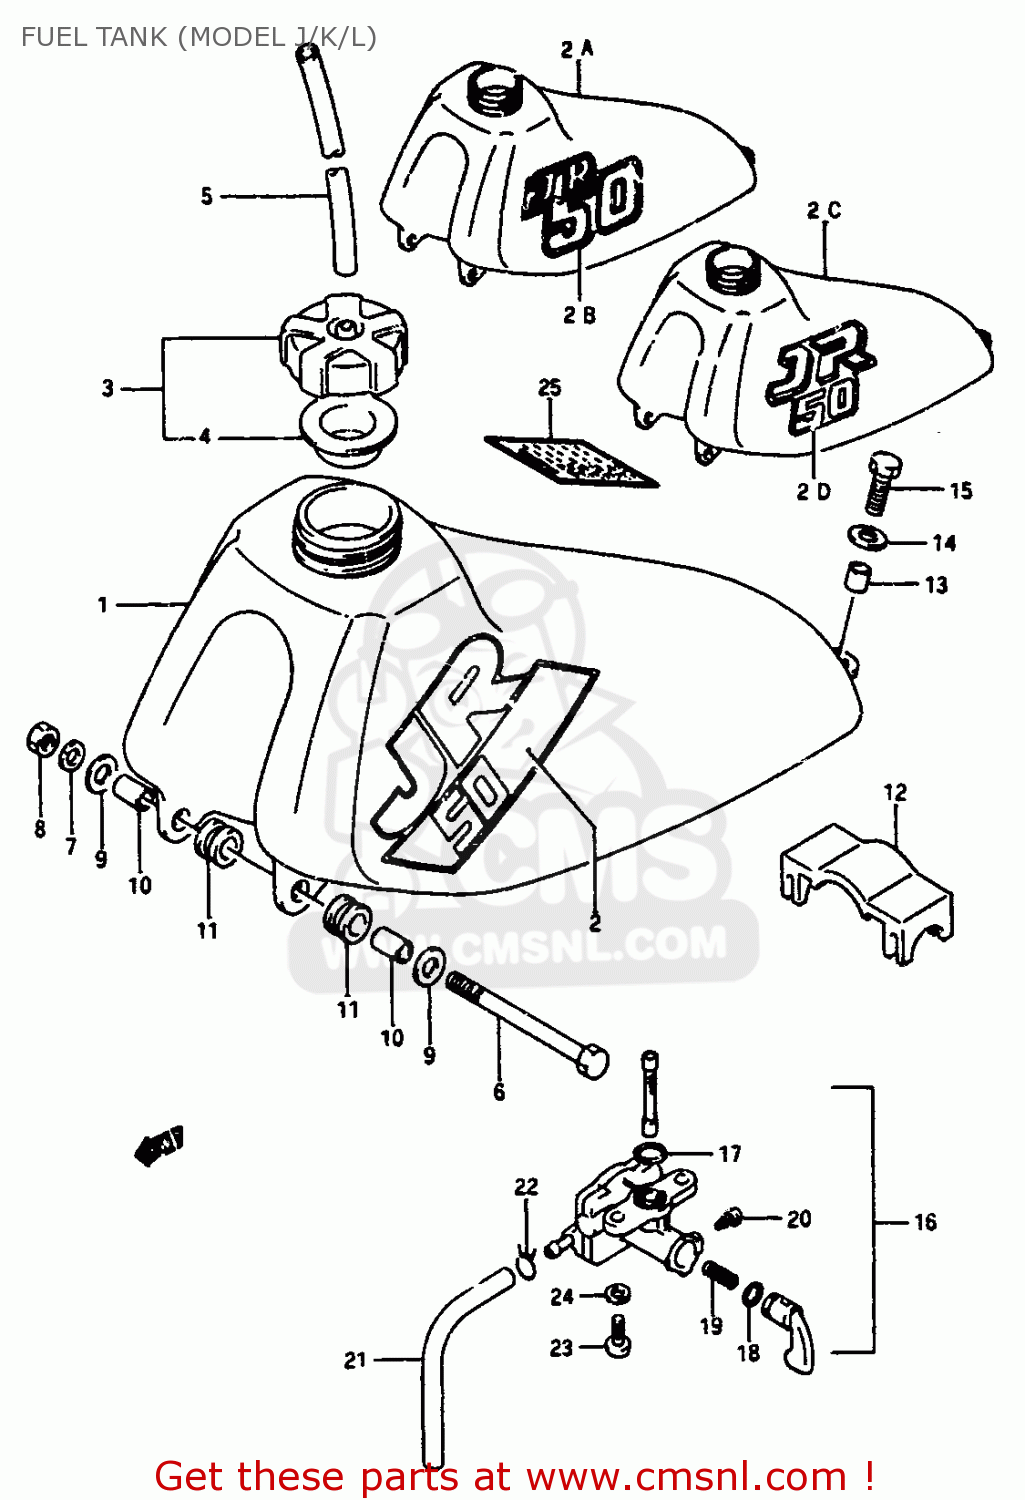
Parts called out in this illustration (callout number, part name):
1	TANK ASSEMBLY,FUEL
2	TAPE SET,FUEL TANK
2A	TANK ASSEMBLY,FUEL
2B	TAPE,FUEL TANK
2C	TANK,FUEL
2D	EMBLEM,FUEL TANK
3	CAP,FUEL TANK FILLER
4	GASKET,FUEL TANK CAP (NAS)
5	HOSE
6	BOLT
7	WASHER,LOCK
8	NUT 6MM
9	WASHER(6.5X18X1)
10	SPACER (6.8X10X11.5)
11	CUSHION
12	CUSHION,FUEL TANK UPR
13	SPACER
14	WASHER(6.5X18X1)
15	BOLT
16	COCK ASSY,FUEL
17	O RING
18	O RING,LEVER
19	SPRING,FUEL COCK VALUE
20	SCREW
21	HOSE
22	CLIP
23	SCREW
24	WASHER,LOCK
25	LABEL (WARNING)
